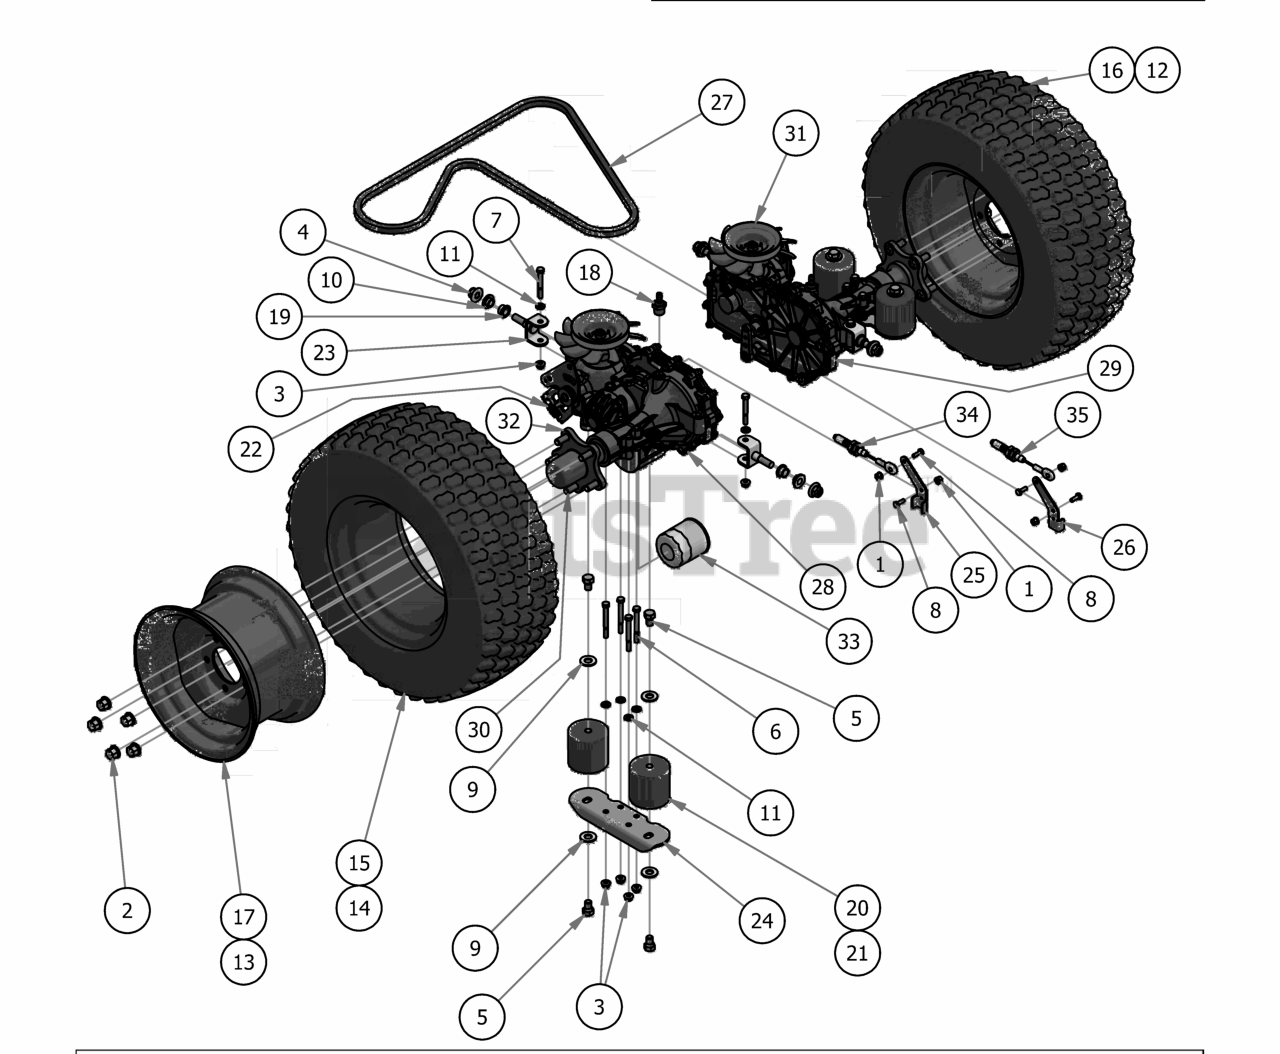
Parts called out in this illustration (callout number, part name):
1	1/4-20 Nylon Insert flange Nut
2	Acorn Lug Nut
3	5/16" Nylon Flange Nut
4	1/2-13 Nylon Flange Nut
5	1/2" x 3/4" Hex Bolt
6	5/16" x 3" Hex Bolt
7	5/16" x 2 1/2" Bolt
8	1/4" x 3/4" Hex Bolt
9	1/2" Washer (Grade 8)
10	.515 ID Nylon Shoulder Washer
11	5/16" Flat Washer
12	Tire and Wheel Assembly (28 and 29) (48" Maverick Only)
13	12 x 7" Black Wheel (48" Maverick Only)
14	23 x 8.50 - 12 Tire (48" Maverick Only)
15	23 x 11 -12 Reaper Turf Tire
16	2019 Maverick Reaper Turf Tire and Wheel Assembly
17	12" Black Wheel
18	45 degree fitting
19	Bronze Bushing - SF - 2024-8
20	Vibration Mount-Green Dot
21	Vibration Mount-Red Dot (48" Maverick Only)
22	Gold Transaxle Spring
23	Maverick Rear Transaxle Pivot Bracket
24	Rear Susp Transaxle Mount
25	Brake Arm Ext (Left)
26	Brake Arm Ext (Right)
27	75.8" Pump Belt
28	3200 Left transaxle
29	3200 right transaxle
30	Transaxle Wheel Stud
31	Fan/Pully Kit for ZT and Maverick
32	Transaxle Hub
34	Brake Cable,18.5"
35	Brake Cable, 24.5"
